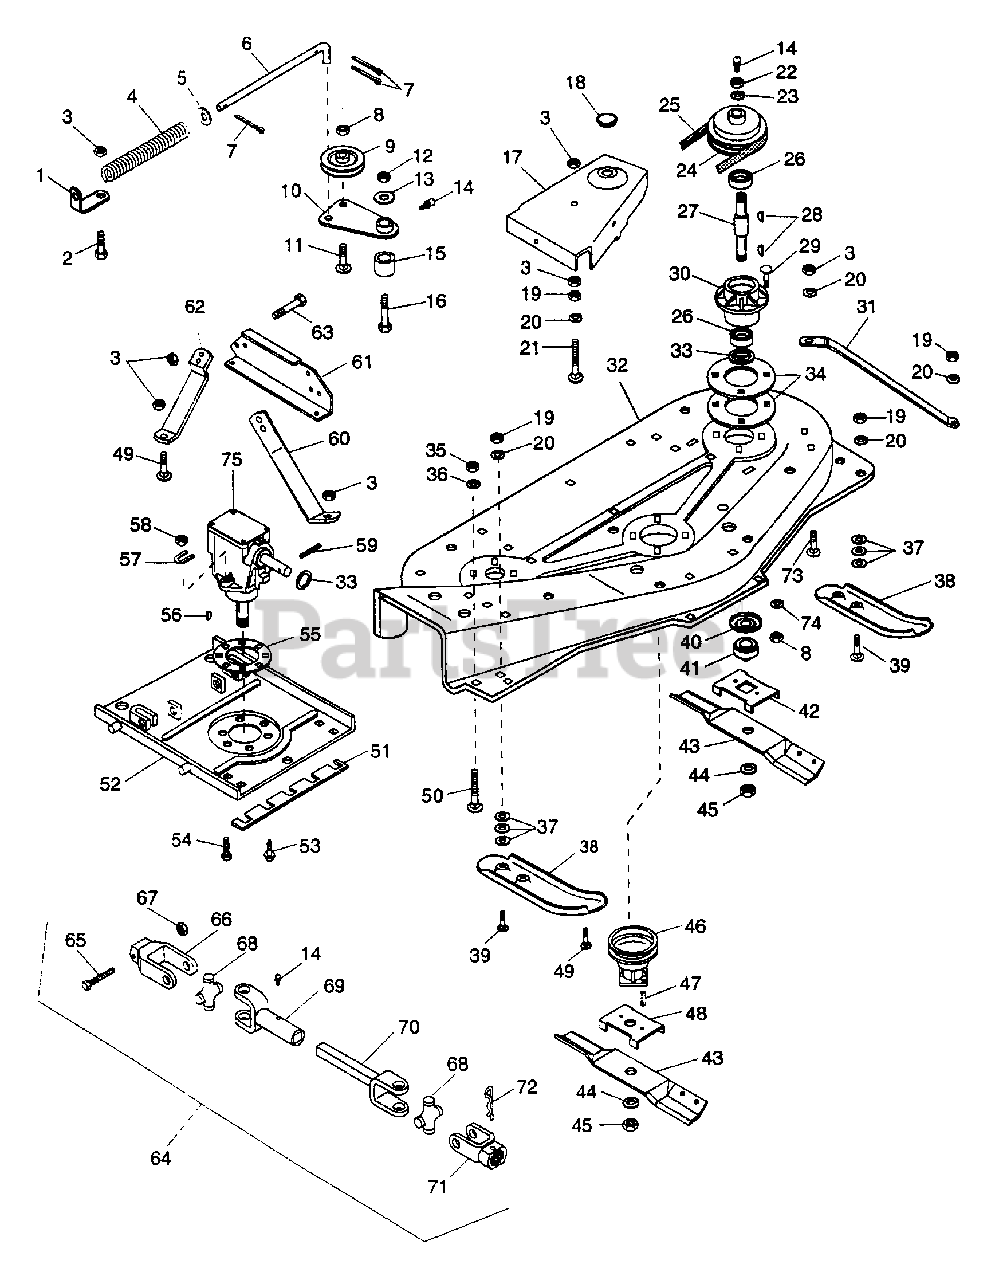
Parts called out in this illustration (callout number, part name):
1	BRACKET
2	BLT-HEX .31-18X.50 GR5
3	NUT-LK .312-18 GR A PL
4	SG-COMP .106X.63X 12.0 WLD 62
5	WSHR-FL-STL.406X.812X.065PL
6	ROD-IDLER SPRING
7	PIN-COTR .09X.75 PL
8	NUT-LK-JAM-CTR .375-16 PL
9	IDLER-FLAT 4.00 X .38 NWHAMSHR
10	IDLER ARM W/ZERK
11	BLT-BTHD .38-16X1.25 GR5
12	NUT-LK-CTR .50-13
13	WSHR-FL-STL .505X.880X.072 PL
14	FTG-LUBE .25-28X.256 YWZC
15	SPACER .512X.747X.968
16	BLT-HEX .50-13X1.50 PL GR2
17	BELT COVER R H 42"
17	BELT COVER L H 42"
18	PLUG BUTTON 1.50
19	NUT-HEX .312-18
20	WSHR-LK .312X.097 PL HVY
21	BLT-RDHDSQNK .31-18X3.25 FTHPL
22	NUT-JAM .75-10 PL
23	WSHR-LK .750X.188 MED PL
25	V-BELT, HA-WRAPPED
26	BRG-BALL .750X1.781X.61
27	SPINDLE SHAFT W/ZERK
28	KEY-WDRF .188X.625X.25 SAE 61
29	BLT-RDHDSQNK .375-16X.75 PL
30	SPINDLE HOUSING
31	SKID BRACE LH
32	MOWER PAN W/DECALS 42"
33	WSHR-FL-STL .754X1.000X.032
34	SPACER, SPINDLE
35	NUT-HEX .375-16
36	WSHR-LK .375X.115 HVY PL
37	WSHR-FL-STL .38X.875X.083 PL
38	SKID
39	BLT-RDHDSQNK .31-18X1.00 PL
40	BEARING SLINGER
41	RETAINER HUB
42	BLADE TRAY 42
44	WSHR-LK .750X.188 MED PL
45	NUT-JAM .75-10 PL
47	PIN-GRV .188X.75 TP A
48	BLADE TRAY - GT 42
49	BLT-RDHDSQNK .312-18X.62 PL
50	BLT-HEX.38-16X2.5FTHD GR2 YWZC
52	MOUNTING PLATE
53	SCR-TAP .312-18X1.0 THH PL TR
54	BLT-HEX .31-18X1.25 PL GR5
56	KEY-WDRF .25X.750X.313 SAE91
58	NUT-LK-TOP .312-18 GR C PL
59	PIN-ROLL .125X1.00
60	BRACE-RIGHT FRONT
61	BRACKET-BRACE
62	BRACE-RIGHT REAR
63	BLT-HEX .31-18X.75 PL GR2
64	PTO ASSEMBLY
65	BLT-HEX .25-20X2.13 GR5
67	NUT-LK TOP .250-20 PL
68	JOURNAL CROSS & BEARING ASSEMB
69	SLIP YOKE
70	YOKE AND SHAFT
72	PIN-HAIR INT .18X1.18X3.25 PL
73	BLT-RDHDSQNK .31-18X.75 GR5 PL
74	WSHR-LK .375X.094 MED PL
75	MOWER GEAR CASE 42" AND NEW 48
